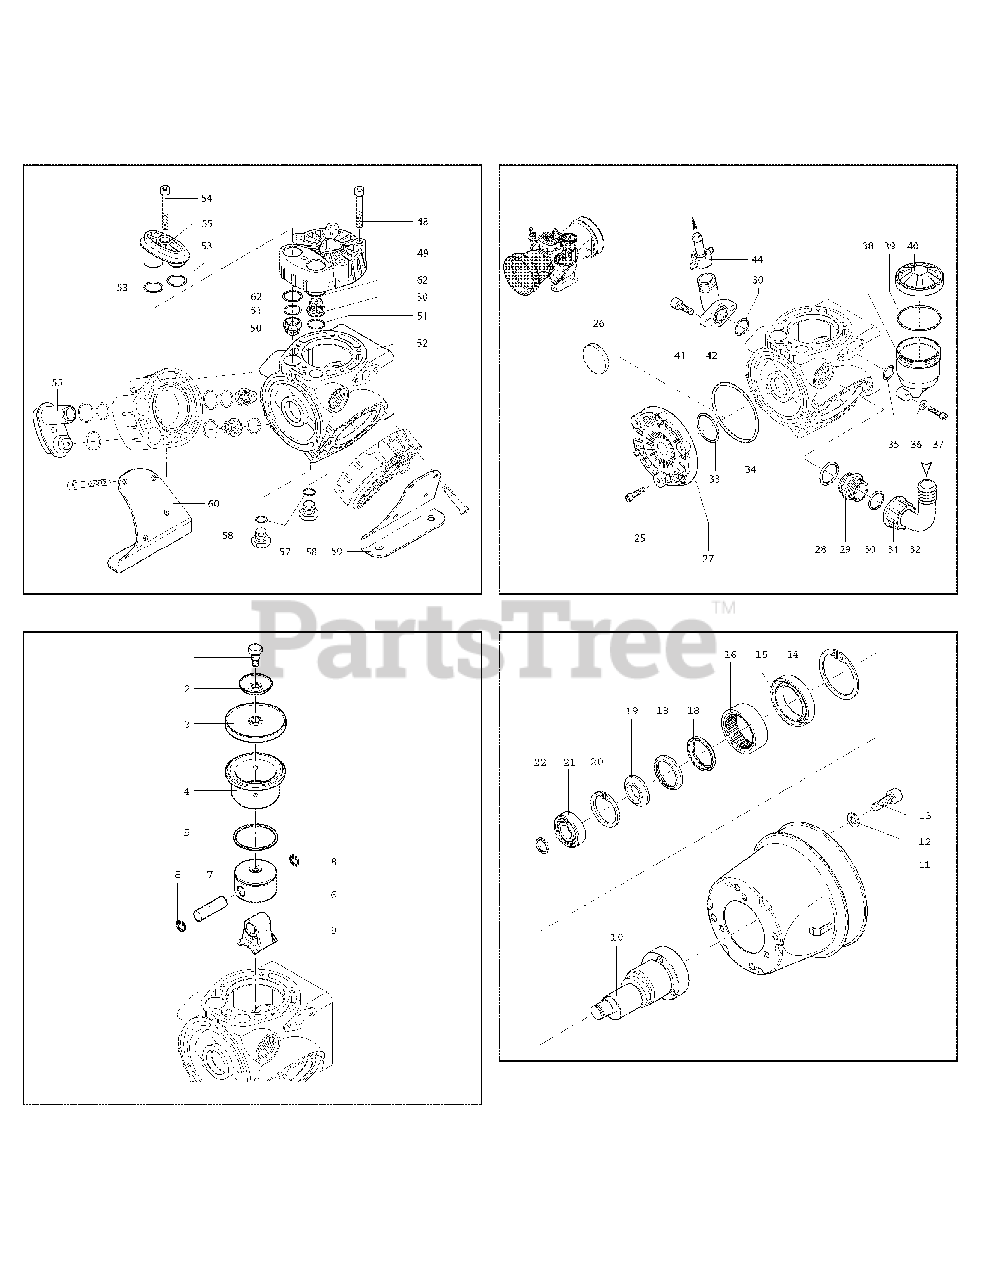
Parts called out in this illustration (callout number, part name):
1	Retaining Bolt
3	Diaphragm Desmopan (Std.)
3	Diaphragm Buna-N (Opt.)
9	Connecting Rod
13	M10 X 16 Bolt
14	Retaining Ring
16	Roller Bushing
18	Connecting Rod Ring
20	Retaining Ring
22	Retaining Ring
27	Suction Manifold
29	Threaded Adapter
32	Elbow (Hose Barb)
38	Oil Sight Glass
40	Black Oil Tank Cap
44	1/2" Fitting and Hose
50	Complete Valve Assembly
55	Right Valve Cover
58	Drain Plug, oil
